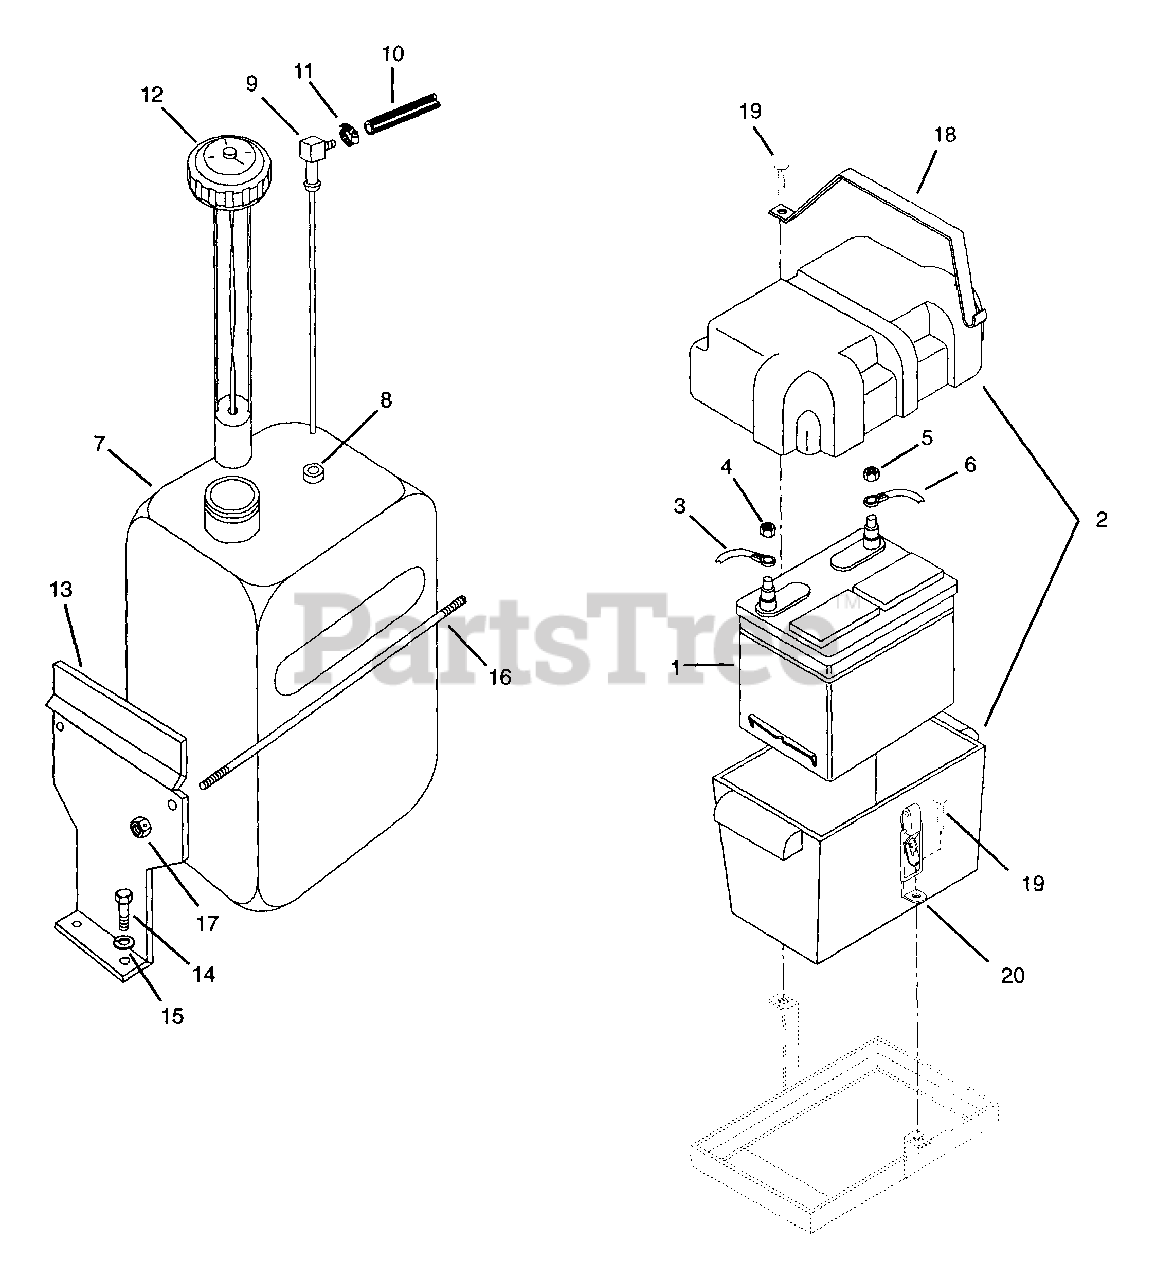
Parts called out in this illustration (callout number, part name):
2	Battery Box
3	Battery Cable (Negative)
4	Nut-Hex .31-18
5	Nut-Hex .38-16
6	Battery Cable (Positive)
7	Tank, Fuel
8	Bushing
9	Fitting, Tank
10	Gas Line - Bulk
11	Hose Clamp
12	Gauge, Fuel
13	Weldment, Tank Bracket
14	Bolt-Hex .32-18 x .75 Grade 5
15	Washer-Lock .31 x .078
16	Rod, Tank
17	Nut-Lock-Center .31-18
18	Strap-Battery Hold Down
19	Bolt-Round Head Square Neck .31-18 x 1.75 Grade 5
20	Latch Assembly-Battery Hold Down
